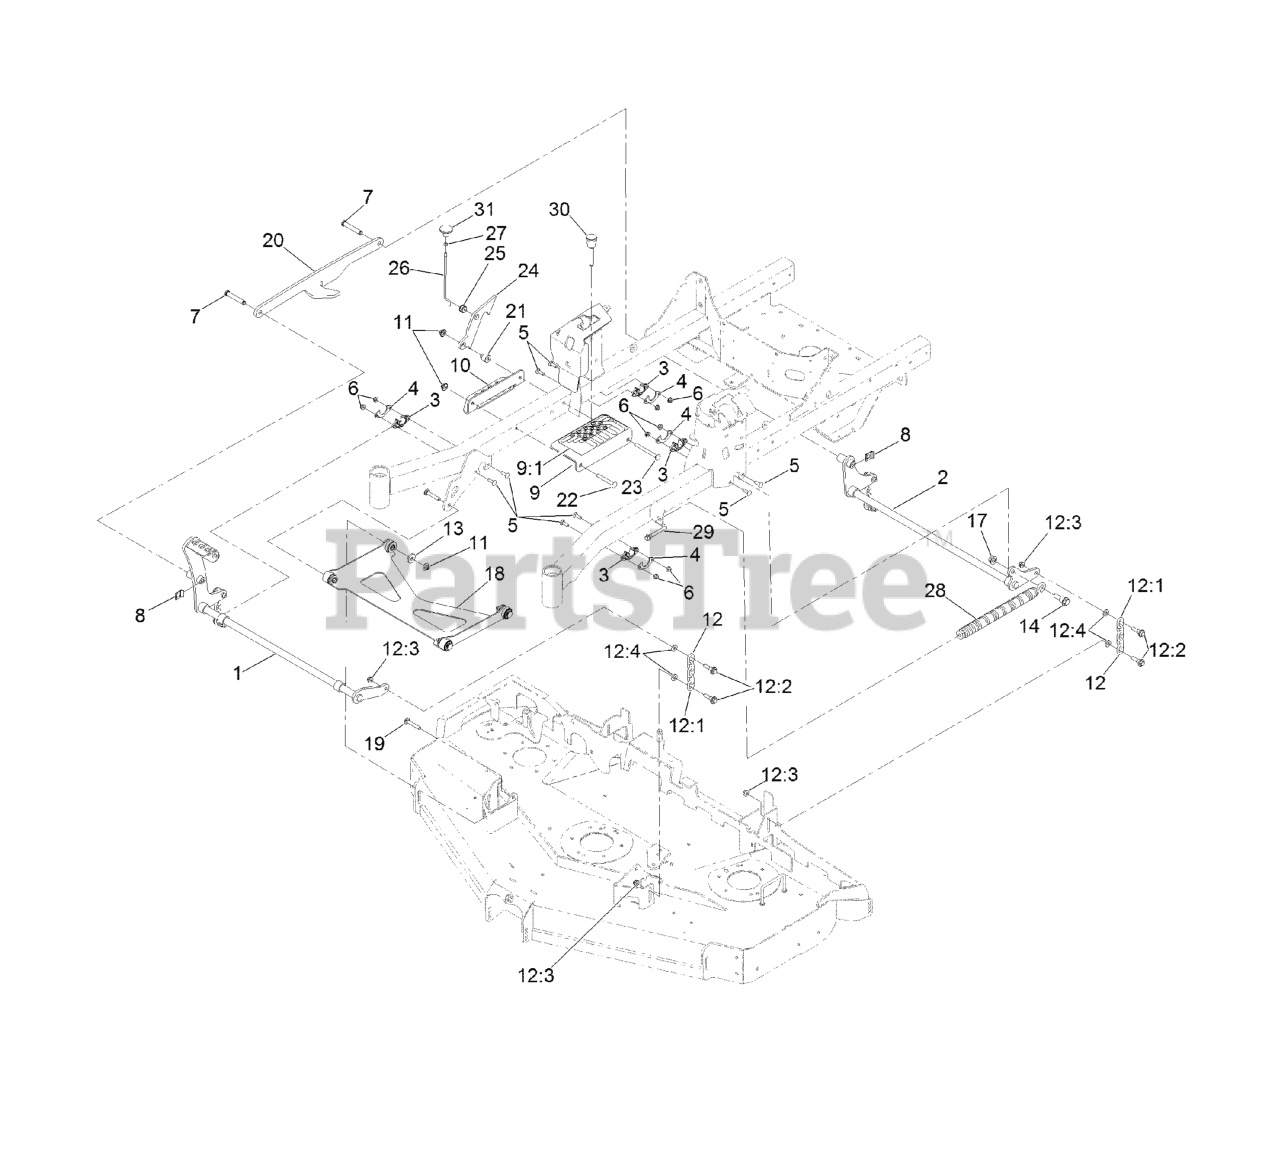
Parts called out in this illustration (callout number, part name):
1	SHAFT-LIFT, DECK
2	SHAFT-LIFT, DECK (REAR)
3	BUSHING-FLANGE
4	GUSSET-LIFT, DECK
5	SCREW-CARR
6	NUT-HF, NI
7	PIN-CLEVIS
8	CLIP-PIN
9	BRACKET ASM
9:1	DECAL-HOC
10	ANGLE-HOC, LOWER
11	Nut-Nyloc 3/8-16 Flg
12	DECK CHAIN ASM
12:1	CHAIN-LIFT, DECK
12:2	BOLT-SHOULDER
12:3	NUT-HF, NI
14	SCREW-SHOULDER, HHF 1/2-13 X 1.12
17	Nut-Lock 1/2-13
18	DECK STRUT ASM
19	Bolt-Carriage 3/8-16 X 2 1/4
20	LINK-LIFT
21	SPACER-STEPPED
22	SCREW-CARR
23	SCREW-CARR
24	PLATE-LOCK, TRANSPORT
25	GROMMET
26	ROD-LOCK, TRANSPORT
27	NUT-JAM
28	SPRING-EXTENSION
29	BOLT-SHOULDER
30	PIN-HOC
